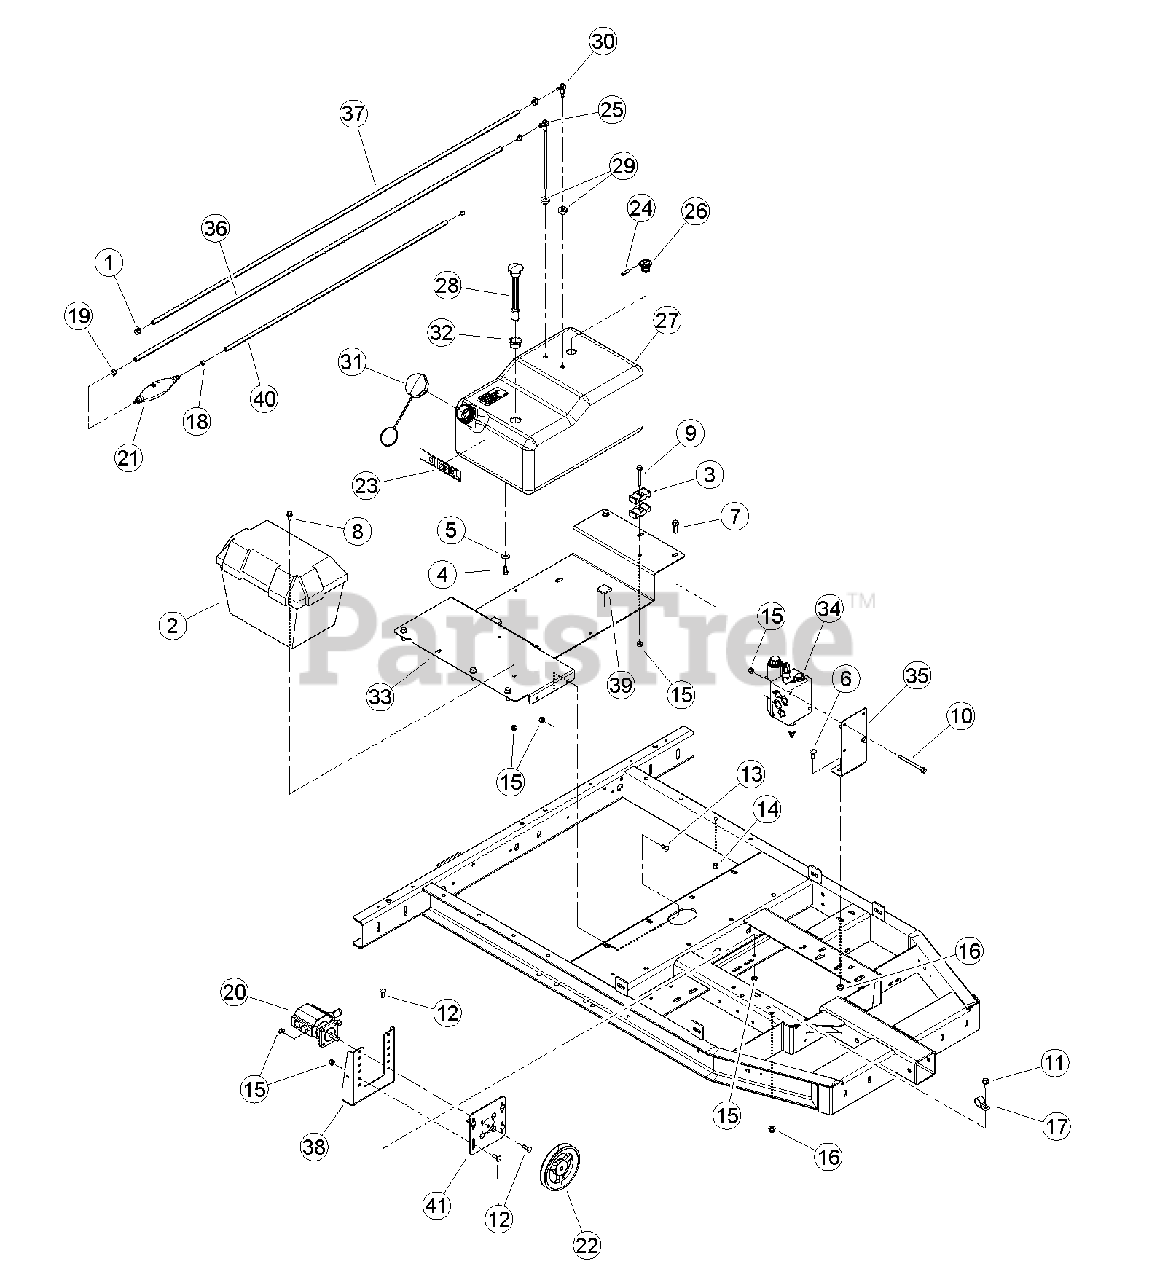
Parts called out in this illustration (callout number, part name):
1	CLAMP, HOSE 5/16 X 5/8 DIA MAX
2	BOX, PLASTIC BATTERY
3	CLAMP, PLASTIC HOSE
4	BOLT, 3/8 X 3/4 GR5 HEX CAPSCREW ZP
5	WASHER, 3/8" FLAT ZP
6	BOLT, 3/8 X 1" GR5 CRG NC ZP
7	BOLT, 3/8 X 1-1/4 FLANGE NC
8	BOLT, 5/16 X 3/4 FLANGE NC
9	BOLT, 5/16 X 2-1/2 FLANGE NC
10	BOLT, 5/16 X 4 SERRATED FLANGE NC
11	BOLT, 3/8 X 3/4 FLANGE NC
12	BOLT, 5/16 X 1" GR5 CRG ZP
13	BOLT, 5/16 X 3/4 GR5 CRG NC ZP
14	NUT, 3/8" NE NYLOCK ZP
15	NUT, 5/16-18 NYLOCK-FLANGE
16	NUT, 3/8-16 NYLOCK FLANGE
17	CLAMP, 1" COATED METAL
18	CLAMP, 15/32 SPRING
19	CLAMP, 9/16 SPRING
20	PUMP, 2 STAGE CW HI/LO 0.605 DISP.
21	PUMP, HAND PRIMER
22	PULLEY, 5.6 - 1/2" BORE FHP B
23	DECAL, DIESEL FUEL
24	CAP, EPDM BLACK .223 ID X 1.0 LG X .06 WALL
25	FITTING, TANK FUEL PICK-UP TUBE 5/16"
26	VALVE, ROLL OVER
27	TANK, ROTOMOLDED FUEL
28	GAUGE, FUEL LEVEL KELCH 100
29	GROMMET, TANK FITTING
30	FITTING, TANK VENT
31	CAP, FUEL TANK VENTED
32	GROMMET, KELCH 100 GAUGE
33	BASE, BATTERY BOX/FUEL TANK
34	ASSEMBLY, HYDRAULIC FEED FLOW VALVE W/ PS
35	PLATE, VALVE MOUNTING
36	HOSE, 63" FUEL LINE
37	HOSE, 63" RETURN LINE
38	BRACKET, MOUNT HYDRAULIC PUMP
39	PAD, FOAM FUEL TANK DAMPER
40	HOSE, 38" FUEL
41	PLATE, HYDRAULIC PUMP
